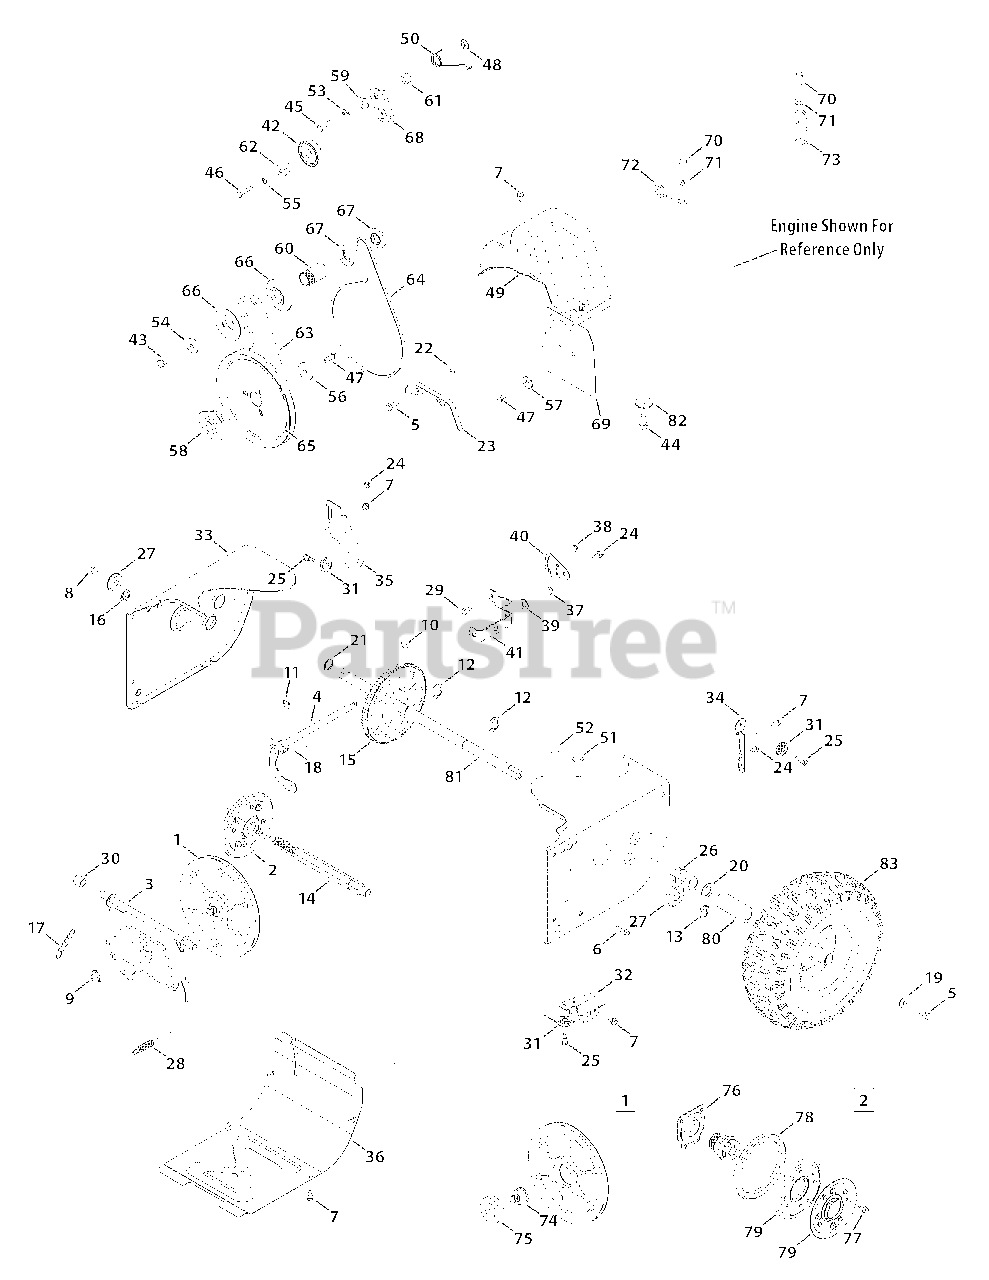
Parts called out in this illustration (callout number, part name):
1	Disc Assembly, Friction Wheel
2	Friction Wheel Assembly, 5.5 OD
3	Friction Wheel Support Bracket
4	Rod Shift Assembly
5	Hex Head Screw, 5/16-24 x .750
6	Taptite Screw, 1/4-20 x 1.000
7	Taptite Screw, 1/4-20 x .625
8	Flange Lock Nut, 3/8-16
9	Flange Nut, 5/8-18
10	Hi-pro Key, 3/16 x 3/4 Dia.
11	E-ring
12	Retaining E-ring, .875 Dia.
13	E-ring, .750 Dia.
14	Hex Shaft, 7-Tooth
15	Gear, 80-Tooth
16	Speed Nut, .500
17	Extension Spring
18	Torsion Spring, .750 x .968
19	Bell Washer, .340 x .872 x .060
20	Flat Washer, .793 x 1.24 x .060
21	Flat Washer, .75 x 1.00 x .060
22	Washer, Flat, .385 x .62 x .063
23	Belt Cover
24	Shoulder Screw, .368 x .113, 1/4-20
25	Shoulder Screw, 1/4-28, .340 x .355
26	Hex Flange Bearing
27	Ball Bearing, 17 x 40 x 12
28	Wheel Clutch Cable, 44.95"
29	Hex Head Screw, 1/4-20 x .620
30	Spacer, .508 ID x .75 OD x .68
31	Cable Roller
32	Auger Cable Front Guide Bracket
33	Frame - Red
33	Frame - Black
34	Auger Cable Guide Bracket
35	Drive Cable Guide Bracket
36	Frame Cover - Red
36	Frame Cover - Black
37	Flange Lock Nut, 5/16-18
38	Flange Lock Nut, 1/4-20
39	Washer, Flat, .469 x .875 x .105
40	Speed Selector Pivot Bracket
41	Speed Selector Shift Bracket
42	Idler Pulley Assembly
43	Hex Screw, 3/8-24 x 1.25
44	Sems Screw, 3/8-16 x 1.00
45	Hex Screw, 5/16-24 x 1.25
46	Hex Screw, 1/4-20 x 1.25
47	Hex Screw, 5/16-24 x .875
48	Push-on Nut, .25 Dia.
49	Belt Cover - 28" & 30" Models
49	Belt Cover
49	Belt Cover - 24" & 26" Models
50	Torsion Spring, .850 ID x .333
51	Plug, 3/8 ID
52	Plug, 1/2 ID
53	Lock Washer, 5/16
54	Flat Washer, .406 x 1.25 x .157
55	Washer, Lock, 1/4
56	Flat Washer, .34 x 1.50 x .150
57	Shoulder Space
58	Adapter Pulley, .75 Dia.
59	Shoulder Spacer, .3175 x .5 x .0975
60	Spacer, .875 ID x 1.185 OD
61	Spacer, .340 x .750 x .330
62	Shoulder Space, .260 x .785 x .538
63	Auger Drive Belt - 28" & 30" Models
63	Auger Drive Belt - 24" & 26" Models
64	Wheel Drive Belt - 28" & 30" Models
64	Wheel Drive Belt - 24" & 26" Models
65	Auger Drive Pulley, 8.1 x .5
66	Pulley Half, 2.600 OD
67	Pulley Half, 3/8 x 1.716 OD
68	Wheel Drive Idler Bracket
69	Cover Plate - 28" & 30" Models
69	Cover Plate - 24" & 26" Models
70	Hex Head Screw, 1.25 x 20
71	Washer, Flat, .330 x .630 x .0635
72	Cable Guide
73	Cable Guide
74	Disc Bearing Friction Pin
75	Ball Bearing, 30 x 55 x 13
76	Bearing Assembly
77	Screw, 1/4-14 x .625
78	Friction Wheel Rubber
79	Friction Wheel Plate
80	Spacer, 1.25 x .75 x 3.0
81	Axle, .75 x 22
82	Washer, Flat, .38 x 1.38 x .125
83	Snow Hog Wheel, 13 x 4 x 6 - 24" Models
83	Snow Hog Wheel, 15 x 5 x 6 - 26" & 28" Models
83	Snow Hog Wheel, 15 x 4.8 - 30" Models
